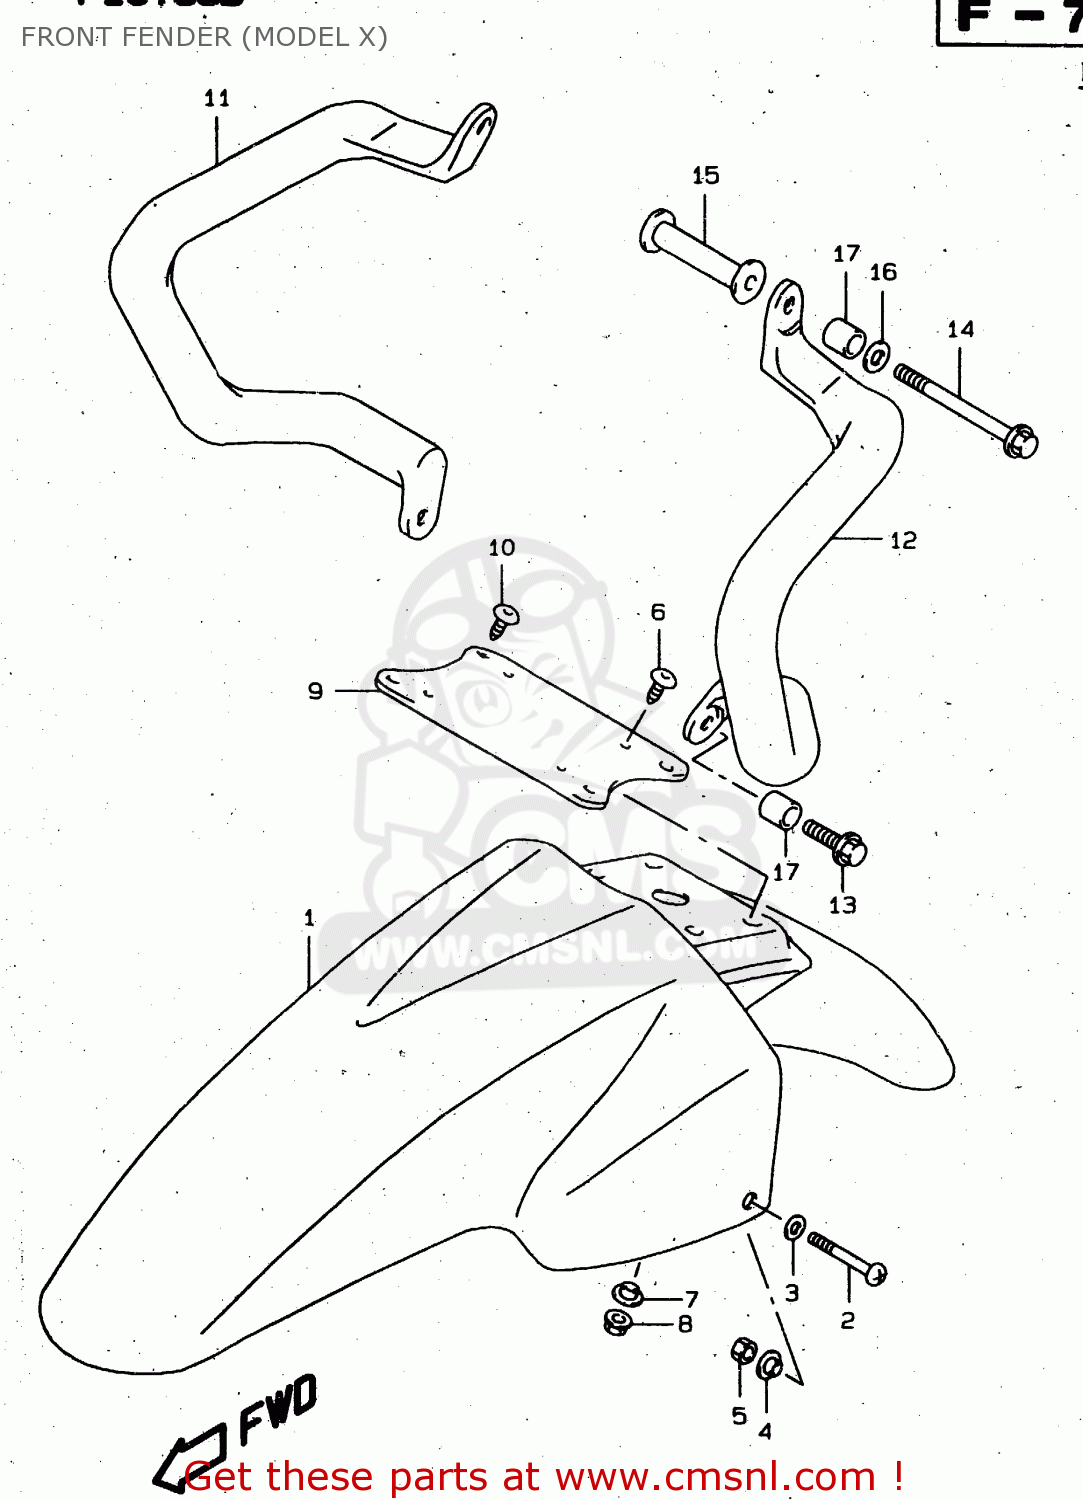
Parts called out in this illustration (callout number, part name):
1	FENDER,FR
2	SCREW
3	WASHER(6.5X18X1.6)
4	WASHER
5	NUT
6	SCREW(5X16)
7	WASHER
8	NUT
9	BRACE,FR FENDER
10	BOLT, BRACE
11	BAR,EXTERIOR,R
12	BAR,EXTERIOR,L
13	BOLT(6X16)
14	BOLT
15	SPACER,EXTERIOR BAR,L
16	WASHER(6.5X18X1.6)
17	SPACER(6.1X8X7)
